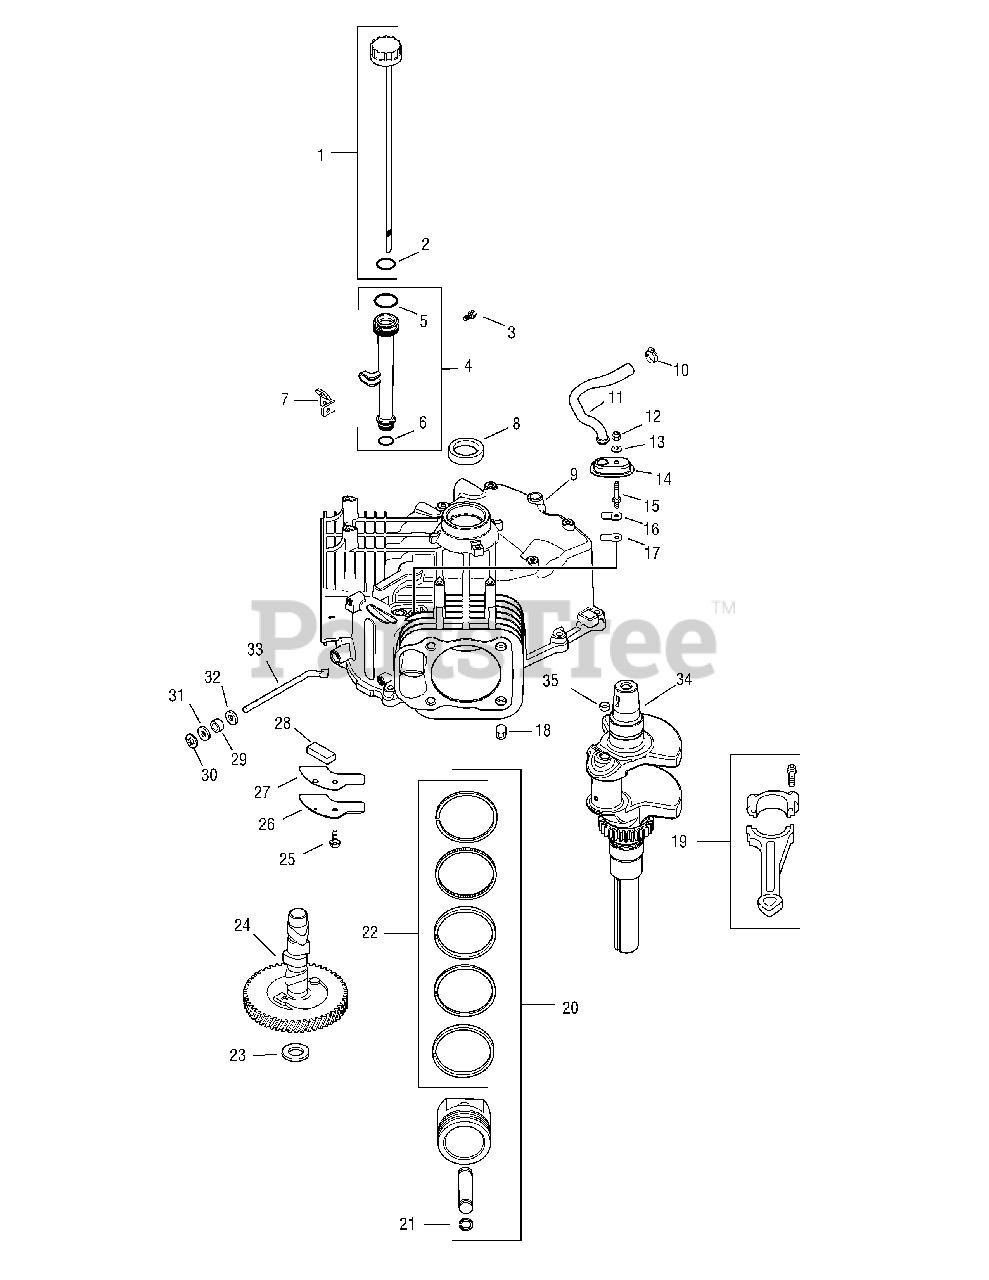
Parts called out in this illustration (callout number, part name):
1	Dipstick Kit (Inc. 2)
2	O-Ring
3	Hex Flange Screw, M5 x 0.8 x 16
4	Oil Fill Tube (Inc. 5 & 6)
5	Upper Oil Fill Tube O-Ring
6	Lower Oil Fill Tube O-Ring
7	Oil Fill Tube Bracket
9	Crankcase (Use: Mini-block KH-32-782-01)
10	Hose Clamp
11	Breather Hose
12	Hex Lock Nut, M5 x 0.8
13	Sealing Washer
14	Breather Housing
15	Breather Cover Stud
16	Breather Reed Retainer
17	Breather Reed
19	Connecting Rod (Std.)
20	Piston w/ Ring Set (Std.) (Inc. 20 & 21)
21	Piston Pin Retainer
22	Ring Set (Std.)
22	Ring Set (.25)
23	Camshaft Shim (Yellow)
23	Camshaft Shim (Red)
23	Camshaft Shim (Black)
23	Camshaft Shim (White)
23	Camshaft Shim (Blue)
23	Camshaft Shim (Green)
23	Camshaft Shim (Gray)
25	Hex Flange Screw, M6 x 1.0 x 16
26	Breather Cover
27	Breather Cover Gasket
28	Breather Filter
29	Governor Cross Shaft Seal
30	Retainer Ring
32	Flat Washer, 1.4
33	Governor Cross Shaft
34	Crankshaft
